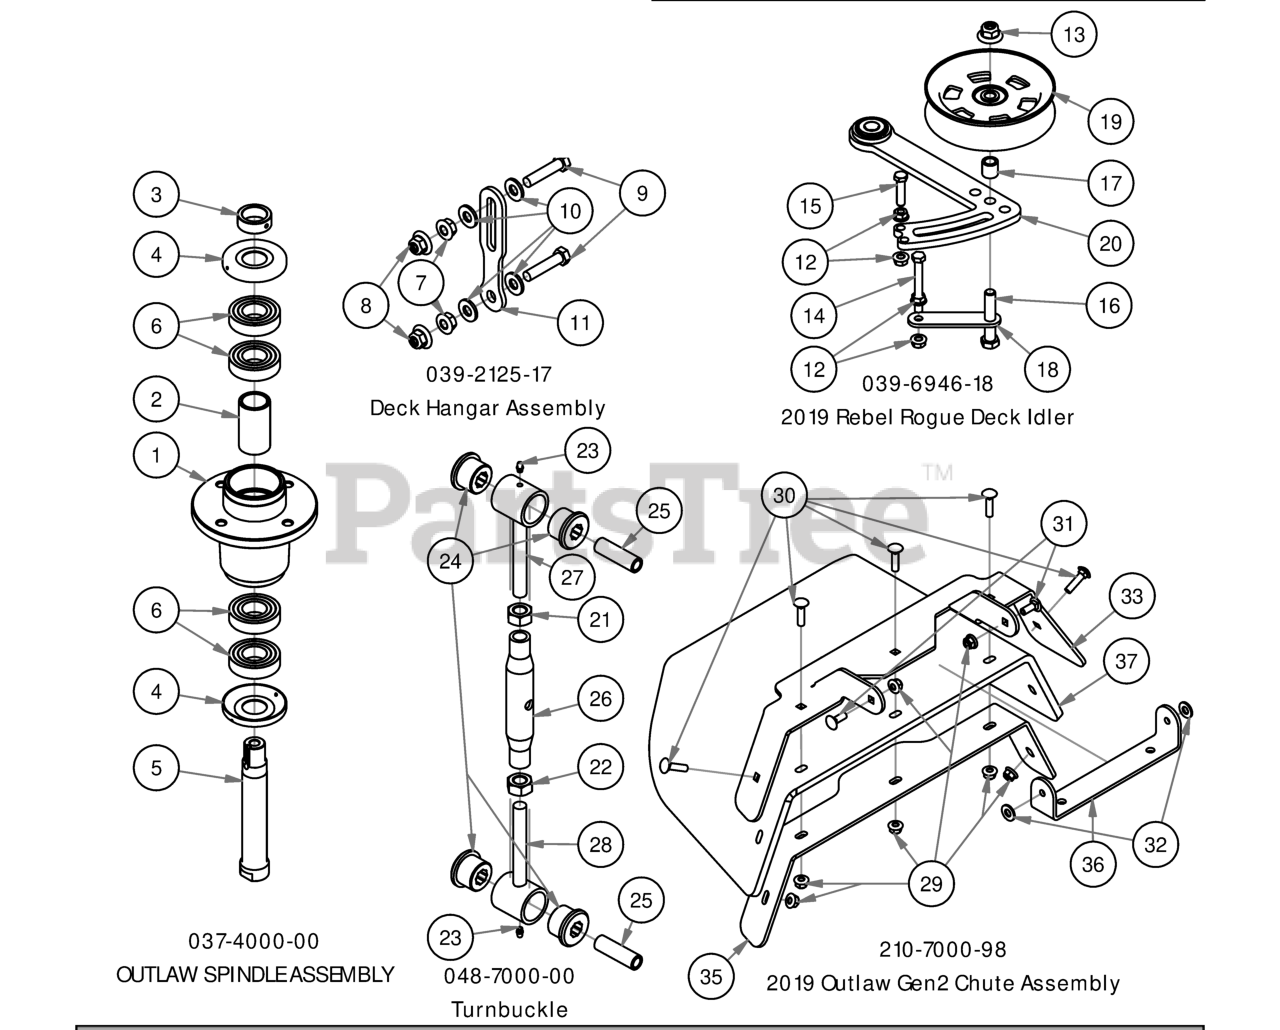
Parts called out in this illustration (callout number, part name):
1	4000 Series Spindle Housing
2	4000 Series Spindle Spacer
3	Locking Collar w/ 1/4"-20 Set Screw
4	Spindle Dust Cap
5	Spindle Shaft
6	Bearing - 6206
7	1/2" Flange Nut
8	1/2-13 Nylon Flange Nut
9	1/2-13X 2-1/4 GR Hex Bolts
10	.505 Nylon Spacer
11	Deck_Hanging_Tab
12	3/8" Flange Nut
13	1/2-13 Nylon Flange Nut
14	3/8-16x3 grade 5 hex bolt
15	3/8 x 1.5" Bolt
16	1/2" x 2 3/4" Hex Bolt
17	Spacer 3/4 OD x 1/2 ID x 3\4 Length
18	Belt Tensioner Retainer Plate
19	5" Idler Pully
20	2019 Deck Tensioner
21	Hex Nut, 11/16-12
22	Hex Nut, 11/16-12 Left Handed
23	1/4" Press in Grease Fitting
24	Polyeurethane Bushing
26	2015 Outlaw Toplink Body
27	2015 Outlaw Toplink RH End
28	2015 Outlaw Toplink LH End
29	5/16" Nylon Flange Nut
30	5/16" x 1 1/4" Carriage Bolt
31	5/16" x 7/8" Carriage Bolt
32	.360 ID Plastic Washer
33	2019 Upper Chute Bracket
35	2019 Lower Chute Bracket
36	2019 Chute Hanger
37	2019 Belted Chute with Logo
